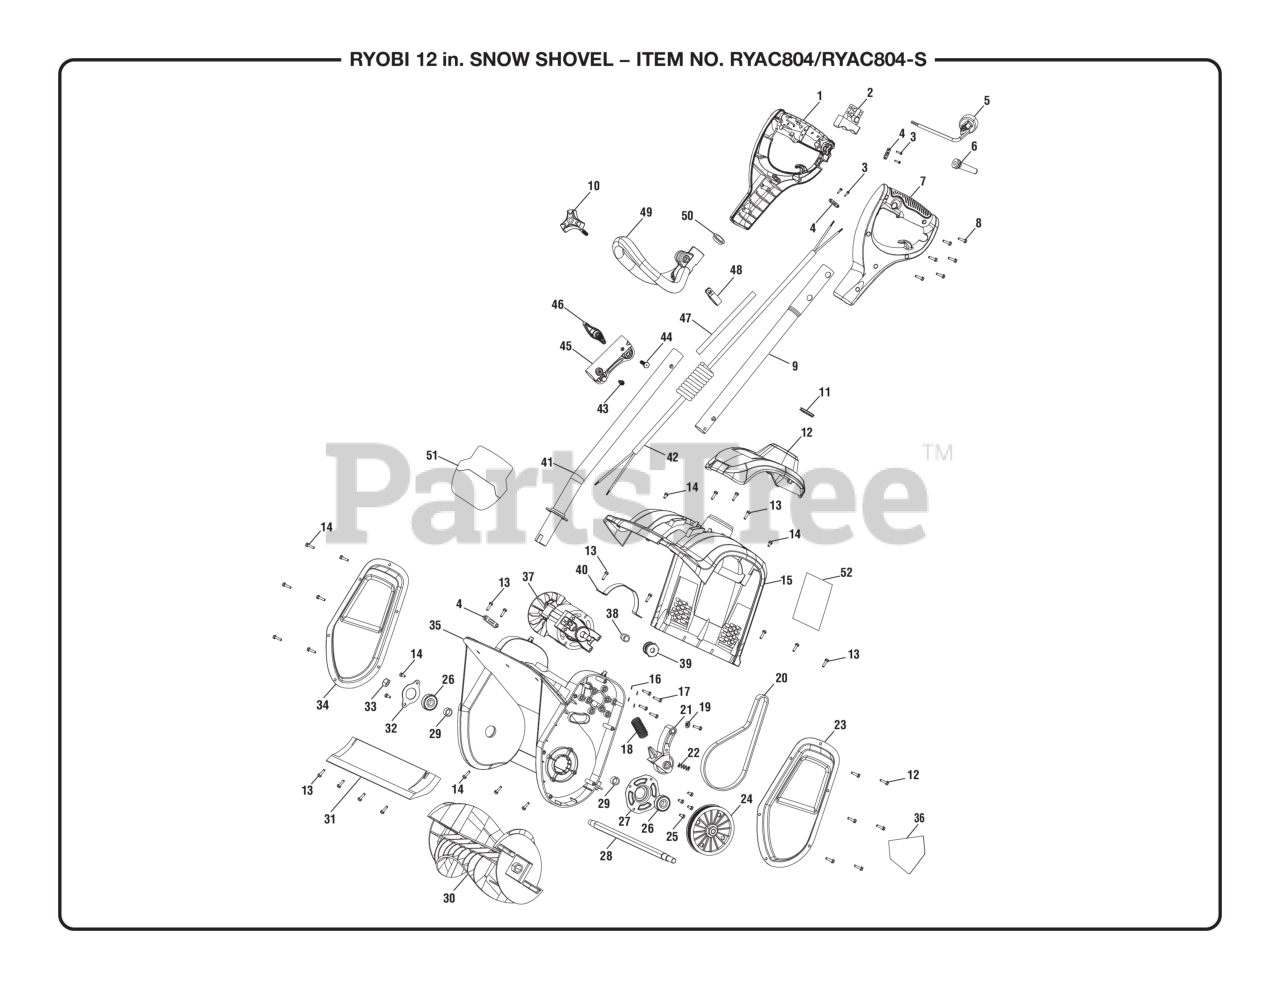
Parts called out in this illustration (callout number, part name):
1	Handle (Right)
3	Screw (M4 x 10 mm)
4	Strain Relief
5	Power Cord
7	Handle (Left)
8	Screw (M4 x 16 mm)
9	Upper Shaft
10	Knob Screw (Front Handle)
13	Screw (M4.2 x 16 mm)
14	Screw (M4.2 x 12 mm)
15	Shroud
17	Screw (Pan Hd.)
18	Compression Spring
21	Idler Assembly
22	Compression Spring
23	Cover (Left)
24	Large Pulley Assembly w/Insert
25	Screw (M4.2 × 9.5 mm)
26	Ball Bearing (6201-2RS)
27	Bearing Plate (Left)
29	Sleeve Bearing
30	Auger (Impeller)
31	Scraper Blade
32	Bearing Plate (Right)
33	Lock Nut (M10)
34	Cover (Right)
35	Lower Housing.
36	Danger Label (No Hands/Feet)
37	Motor Assembly
38	Motor Pulley Spacer
39	Small Pulley
40	Motor Bracket
41	Lower Shaft
42	Coiled Wire Assembly
43	Screw (M5 x 9 mm, Pan Hd.)
46	Knob (Shaft)
49	Front Handle
51	Performance Label
52	Data Label
